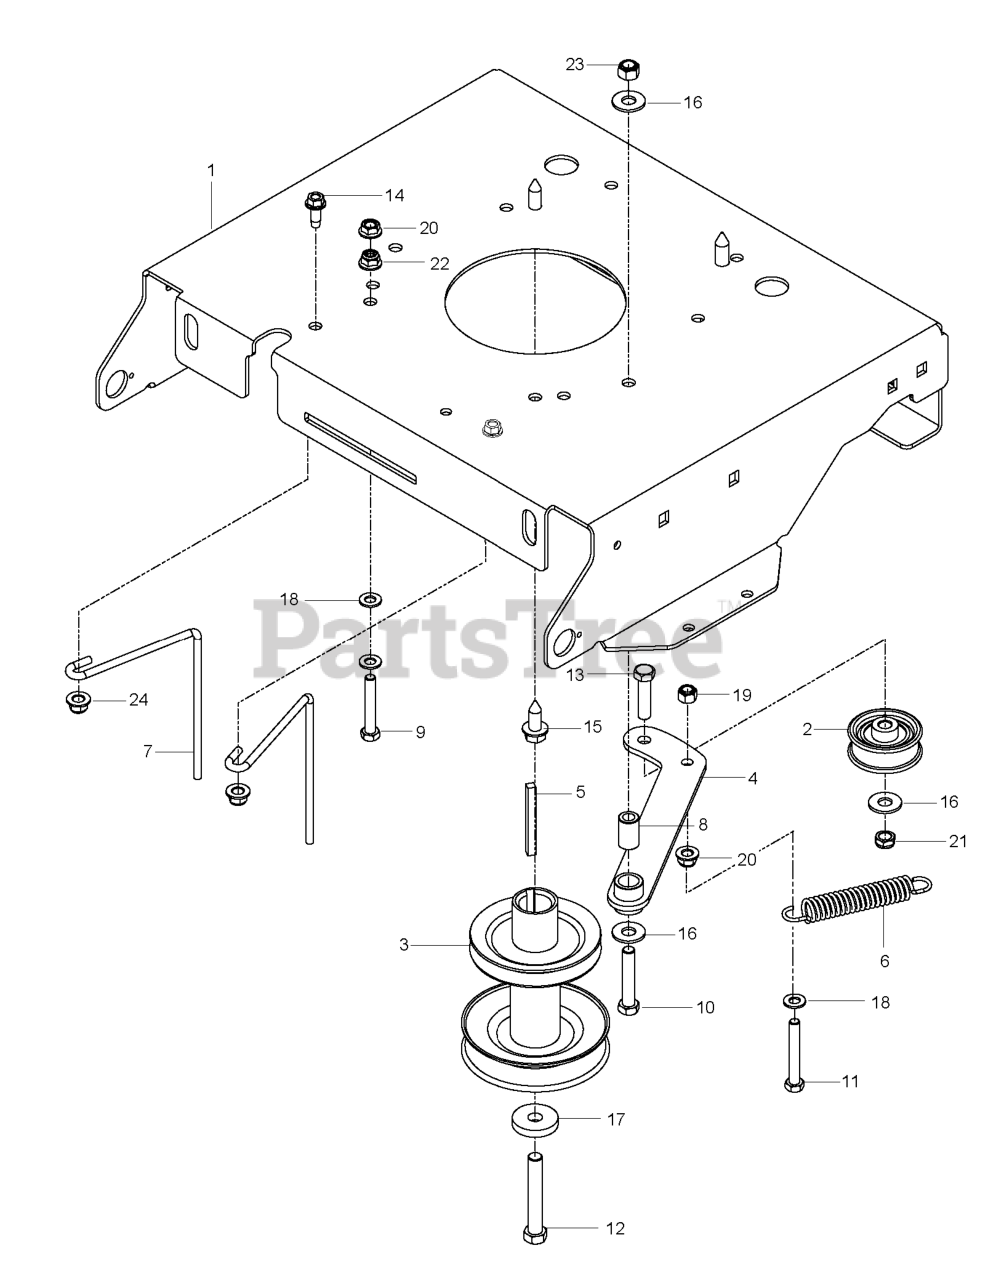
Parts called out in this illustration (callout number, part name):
1	PLATE, ENGINE, ORG
2	PULLEY IDLER
3	PULLEY, ENGINE 30"
4	IDLER WLDT.
5	KEY 1/4 SQ X 2-1/2
6	SPRING - 3.50
7	BELT GUIDE
9	HCS 5/16-18X2
10	HCS 3/8C X 2
12	HCS 7/16-20 X 2-3/4
13	HCS 3/8C X 1 1/2
14	BOLT 3/8-16 X 1.0
15	HHFS 3/8-16 X 1.0 THD FORMING
16	WASHER 3/8 FLAT
17	WASHER .43X1.38X.25
18	FLAT WASHER 5/16 SAE
19	NUT 5/16 NYLOC
20	NUT 5/16C WHIZ
21	NUT HEX 3/8-16 NYLON, THIN
22	5/16-18 NYLOC FLANGE NUT
23	NUT 3/8-16 NYLOC
24	NUT 3/8-16 HEX FLG NYLOC ZD
